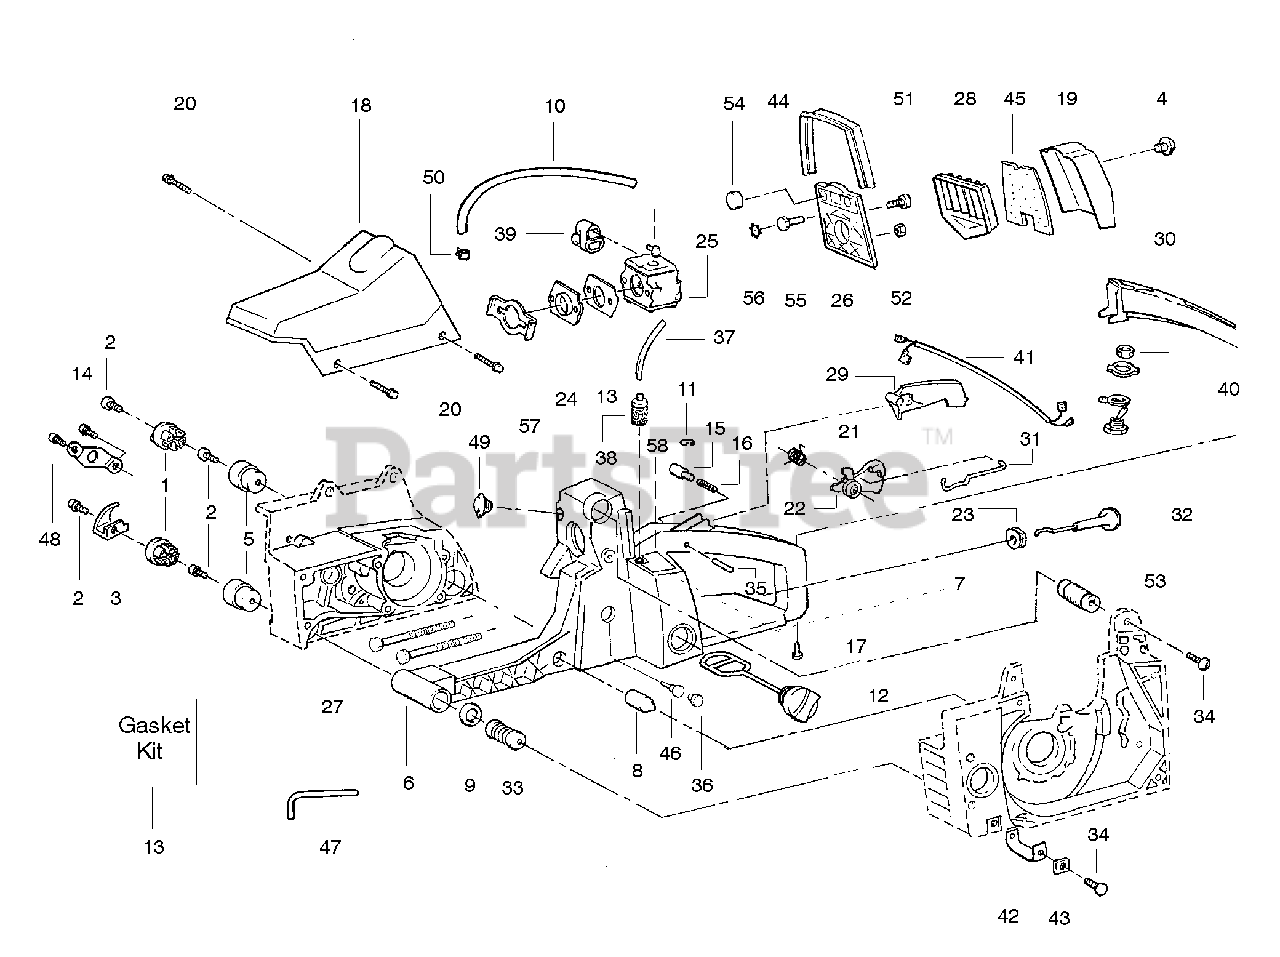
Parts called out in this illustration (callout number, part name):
1	Retainer-Chain Catcher
3	Chain Catcher
4	Knob-Carb. Cover
5	Lower Isolator
6	Rear Handle & Fuel Tank
7	Seal Carb. Cover-Left
8	Isolator Limiter
10	Impulse Line Kit
11	"C" Clip
12	Fuel Cap Ass'y (Incl. "O" Ring)
13	Gasket Kit
15	Throttle Lock
16	Throttle Lock Spring
18	Cylinder Shield
19	Carb. Cover Ass'y.
21	Trigger Latch Spring
22	Throttle Trigger
24	Bracket-Intake
25	Carburetor Kit
26	Air Filter Base
27	Carb. Mounting Stud
28	Air Filter Non-Woven
28	Air Filter Nylon Mesh
29	Throttle Lockout
30	Rear Handle Cover
31	Throttle Wire
32	Choke Knob
33	Isolator Kit
34	Screw
35	Dowel Pin
36	Plug-Bronze Vent
37	Fuel Line Kit
38	Fuel Filter Ass'y.
39	Carb. Grommet
40	Switch Kit
41	Lead Wire Ass'y.
42	AV Strap
43	Strap Retainer Plate
44	Sound Strip
45	Sound Foam
46	Check Valve
47	Hex Wrench 5/32
49	Plug-Air Box
51	Screw-Air Filter Base
52	Nut-Air Filter
53	Cylinder Mount Ass'y.
55	Screw-Carb Knob
56	Retaining Ring
57	Bracket-Carb Stud
58	Seal Carb Cover-Right
